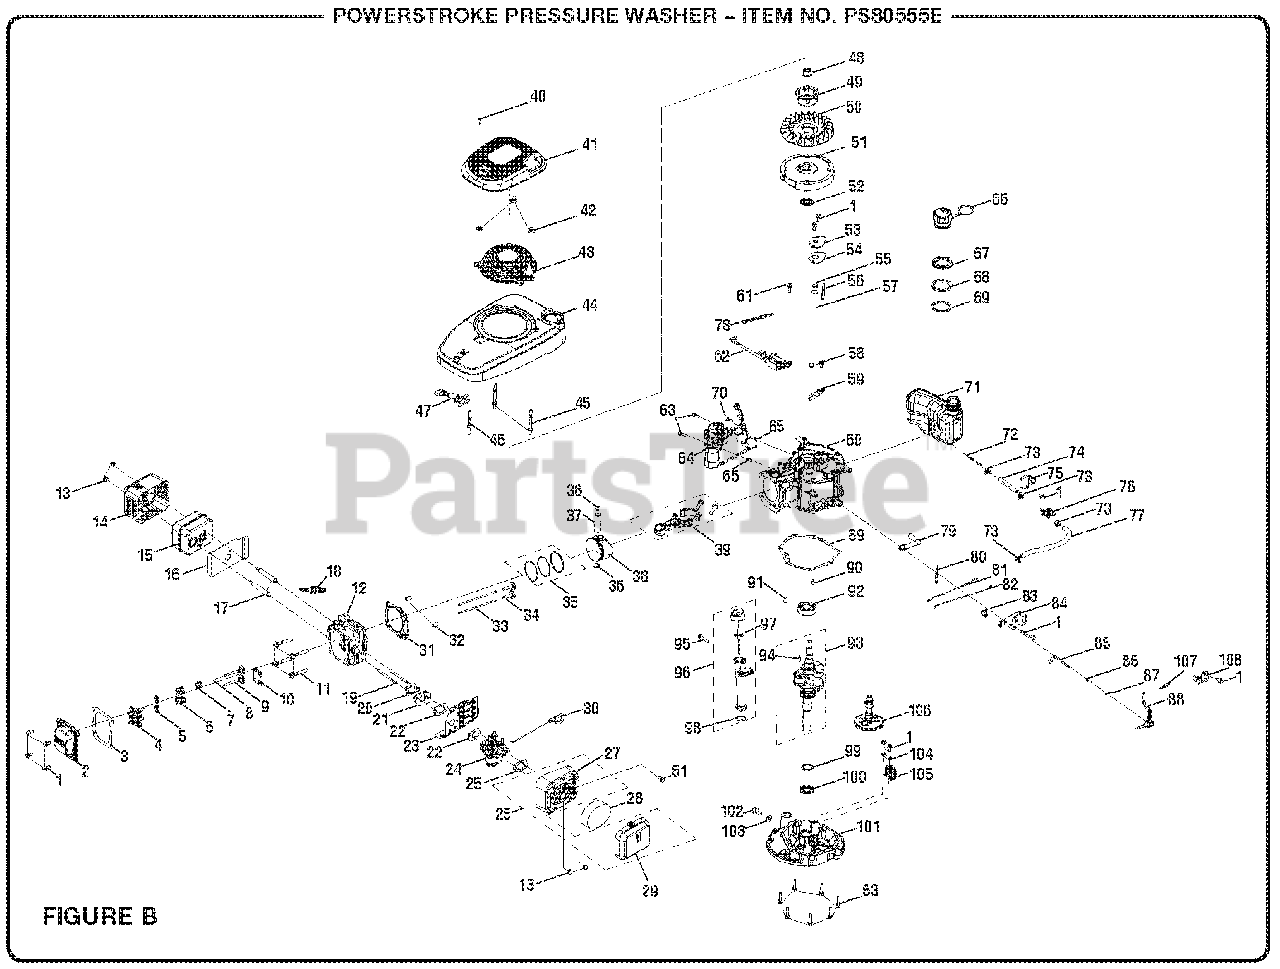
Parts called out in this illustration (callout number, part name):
1	Bolt (M6 x 14 mm, 100011262-0003)
2	Valve Cover (100002308)
3	Valve Cover Gasket (100010174)
4	Rocker Arm Assembly (100004421)
5	Valve Spring Seat (100004580)
6	Valve Spring (100004565)
7	Intake Valve Seal (100004598)
8	Intake Valve (100004523)
9	Exhaust Valve (100004547)
10	Rocker Arm Base (100063679)
11	Bolt (M8 x 54 mm, 100002461-0001)
12	Cylinder Head (100066426)
13	Nut (M6, 100011452-0003)
14	Muffler Guard (100062227)
15	Muffler (100006317)
16	Muffler Gasket (100066439)
17	Stud (M6 x 95 mm, 100010346)
18	Spark Plug (100009378)
19	Stud (M6 x 87 mm, 100010348)
20	Carburetor Insulator Gasket (100005560)
21	Insulator (100005603)
22	Carburetor Gasket (100005919)
23	Shroud (100066441)
24	Carburetor (100062054)
25	Air Filter Gasket (100005946)
26	Air Filter Assembly (100004665)
27	Air Filter Base (100004992)
28	Air Filter Element (100004762)
29	Air Filter Cover (100004838)
30	Choke Lever (100005729)
31	Cylinder Head Gasket (100010205)
32	Pin (F10 x 16 mm, 100010558)
33	Push Rod (100066141)
34	Tappet (100004262)
35	Piston Ring Set (100003245)
36	Circlip (100003221)
37	Piston Pin (100003125)
38	Piston (100003079)
39	Connecting Rod Assembly (100030472)
40	Screw (M4.2 x 25 mm, 100011004)
41	Blower Housing (100032081-0002)
42	Nut (M6, 100008477-0001)
43	Recoil Starter (100007217-0011)
44	Inner Shroud (100061966-0002)
45	Stud (M6 x 78.5 mm, 100010302)
46	Stud (M6 x 74 mm, 100010303)
47	Ground Wire (100062204)
48	Nut (M14, 100011462-0001)
49	Starter Cup (100007546)
50	Cooling Fan (100007027)
51	Flywheel (100054228)
52	Oil Seal (ID22 x OD35 x 6t, 100017640)
53	Breather Cover (100004053)
54	Oil Filter Gasket (100010260)
55	One-Way Valve Spring (100008440)
56	Breather Filter Screen (100004065)
57	Breather Valve (100004085)
58	Bolt (M6 x 12 mm, 100011261-0004)
59	Shield (100066440)
60	Crankcase (100065634)
61	Bolt (M6 x 20 mm, 100011266-0004)
62	Ignition Module (100062088)
63	Bolt (M6 x 28 mm, 100011269-0003)
64	Electric Starter (100071398)
65	Pin (M8 x 8 mm, 100010547)
66	Fuel Cap (100069232)
67	Lock Nut (100008880)
68	Damping Pad (100008662)
69	Damping Pad (100008936)
70	Bolt (M6 x 16 mm, 100011264-0003)
71	Fuel Tank (100061965)
72	Fuel Filter (100009020)
73	Clamp (100005136)
74	Fuel Hose (small, 100017709)
75	Fuel Switch Base (100008908)
76	Fuel Switch (100008895)
77	Fuel Hose (large, 100062199)
78	Clip (100000655)
79	Breather Hose (100002857)
80	Governor Spring (100068846)
81	Idle Spring (100007923)
82	Throttle Linkage (100007955)
83	Clip (100000671)
84	Governor Gear Bracket Assembly (100008082)
85	Governor Gear Shaft (100007971)
86	Oil Seal (ID6 x OD11 x 4t, 100017630)
87	Cotter Pin (100007986)
88	Governor Lever (100062856)
89	Crankcase Gasket (100010156)
90	Pin (M7 x 14 mm, 100010544)
91	Pin (M9 x14 mm, 100010554)
92	Bearing (6205, 100010680)
93	Crankshaft (100059919)
94	Woodruff Key (100010577)
95	Bolt (M6 x 35, 100011271-0003)
96	Dipstick (100004118-0007)
97	Dipstick O-Ring (100004142)
98	Dipstick O-Ring (100004141)
99	Washer (ID25.4 x OD34 x 1t, 100010527-0001)
100	Oil Seal (F25xF40x7/100061527
101	Crankcase Cover (100065632)
102	Ground Bolt (100010272)
103	Washer (ID10 xOD16 x 1.5t,100010459)
104	Governor Gear Mounting Plate (100008451)
105	Governor Gear (100008293)
106	Camshaft (100004293)
107	Governor Spring (100068845)
108	Idle Speed Control (100068787)
